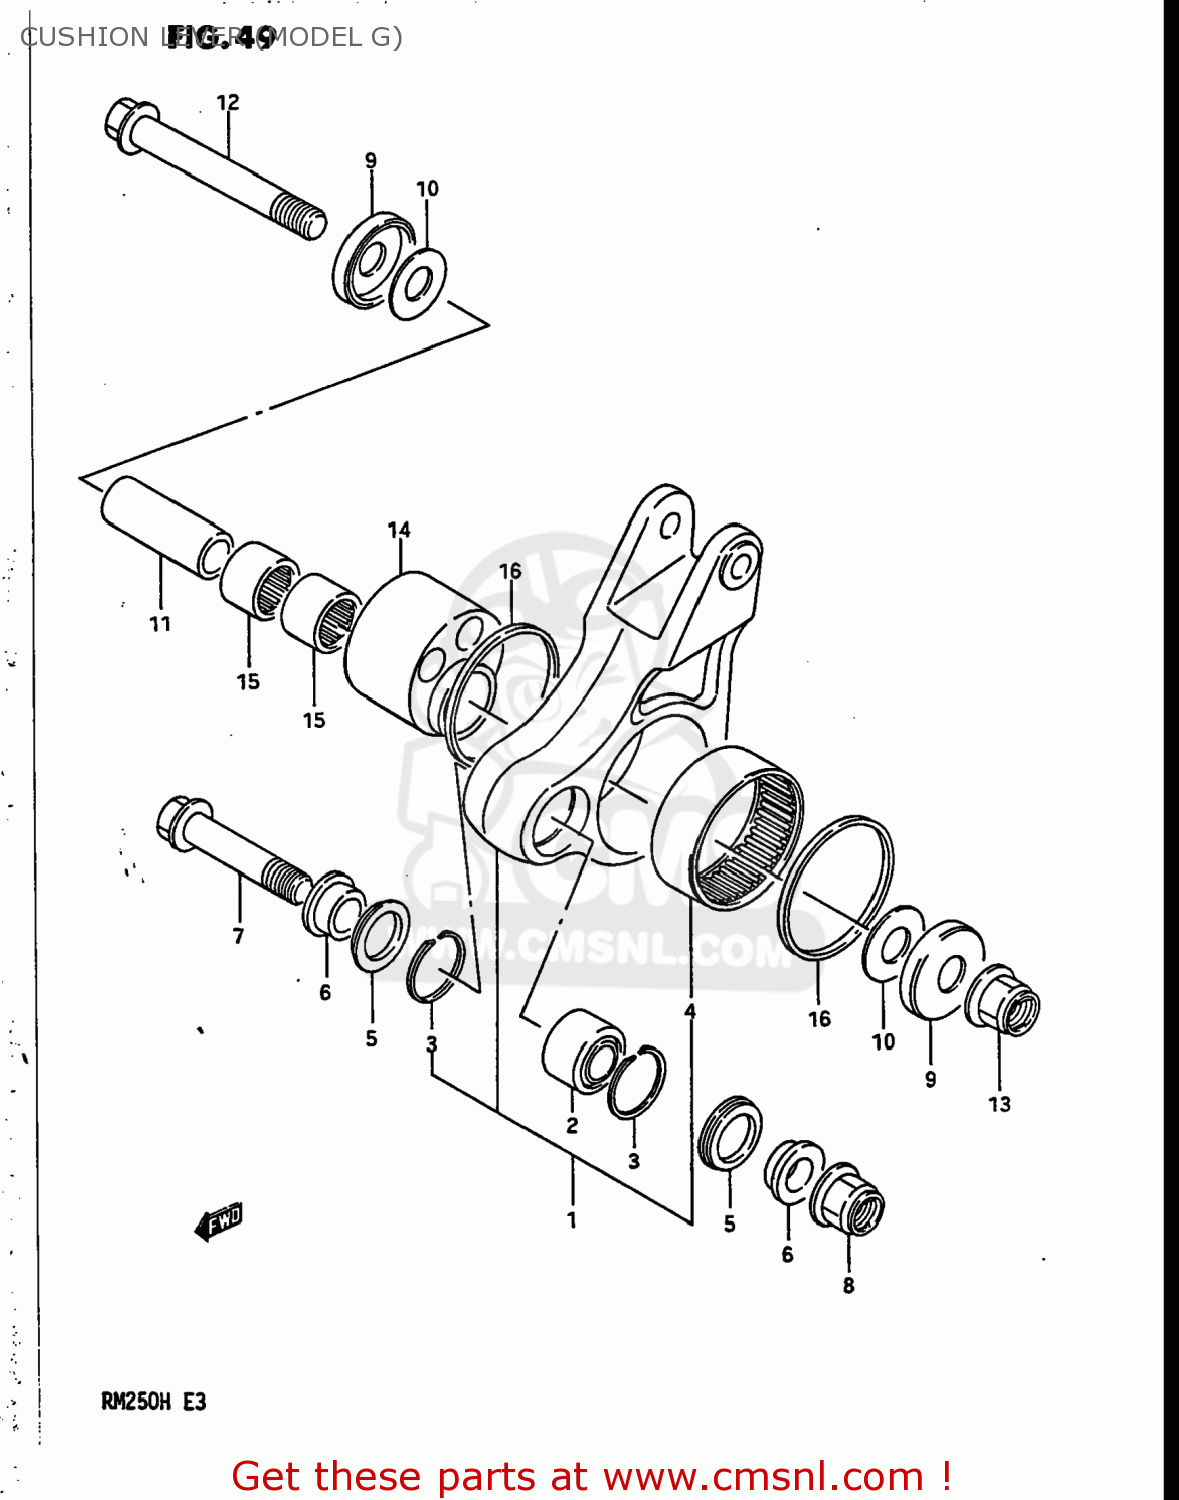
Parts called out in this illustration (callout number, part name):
1	LEVER SET,REAR CUSHION
2	SPHERICAL BEARING (14X3)
3	RING,STOPPER
4	BEARING 55X63X25
5	DUST SEAL,REAR CUSHION,LEFT
6	SPACER,REAR CUSHION LEVER
7	BOLT,RR CUSHION LEVER FR
8	NUT
9	DUST SEAL,RR C
10	WASHER
11	SPACER,RR CUSHION LEVER CTR
12	SHAFT,RR CUSHION LEVER
13	NUT
14	SPACER,RR CUSHION ECCENTRIC
15	BEARING
16	SEAL,REAR CUSHION LEVER
